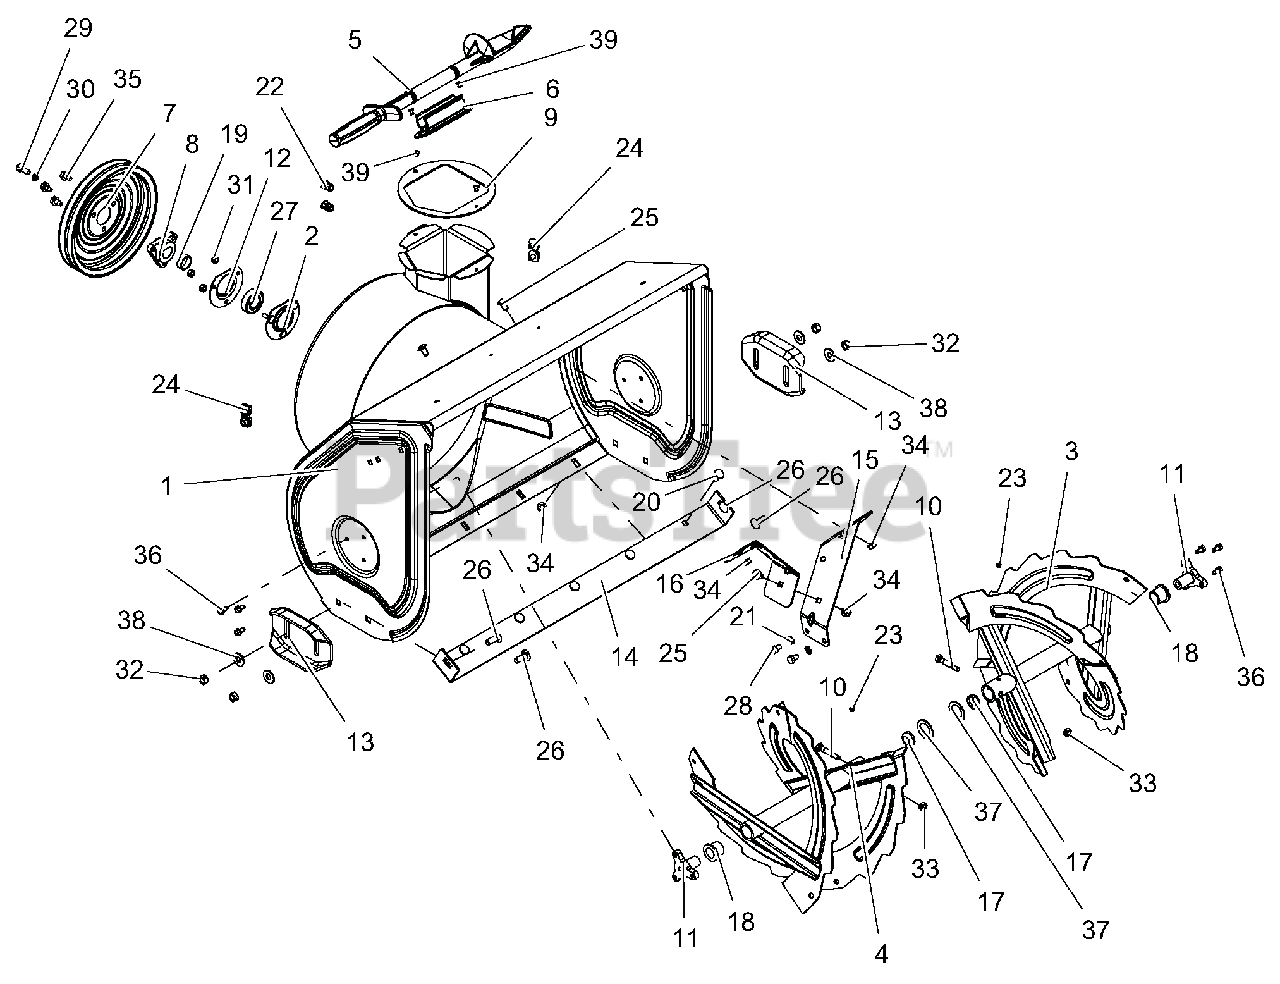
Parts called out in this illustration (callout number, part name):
1	BLOWER HOUSING, 28"
2	BEARING FLANGE
3	RAKE, LH W/ZERK - 28"
4	RAKE, RH W/ZERK - 28"
5	DEVICE, SNOW CLEAN OUT
6	MOUNT, SNOW CLEAN OUT
7	PULLEY, SPIN FORM DUAL GROOVE
8	PULLEY HUB, D-BORE .87 DELUXE
9	BAFFLE, DISCHARGE NECK
10	SHEAR BOLT SERVICE ASSEMBLY
11	SUPPORT, RAKE BUSHING
12	BEARING FLANGE
13	SKID SHOE, REVERSIBLE - ORANGE
14	BLADE, SCRAPER - 28"
15	BRACKET, GEARCASE SUPPORT - LH
16	BRACKET, GEARCASE SUPPORT - RH
17	PLUG, RAKE TUBE
18	BSHG-FLG, NY.778 ID X 1.018 OD
19	BSHG-SPCR .895IDX1.065ODX.353
20	BOLT, MODIFIED HEAD CARRIAGE
21	@WSHR-LK-EXT.326X.599X.031YWZC
22	NUT, THREADED INSERT .38-16
23	ZERK,FITTING .25X.125 DRIVE IN
24	SCR-TAP.31-18X.50 HWH TR YWZ
25	BLT-RDHDSQSHNK.31-18X.62 YZ-LK
26	@BLT-RDHDSHSQNK.38-16X1.0 G5YZ
27	BRG-BALL .876X1.75X.50 RSTFP
28	@BLT-HEX .31-18X.50 GR5 YWZC
29	BLT-HEX .31-24X.75 YWZC GR5
30	WSHR-LK .312X.097 HVY YWZC
31	@NUT-LK-CTR .25-20 YWZC
32	@NUT-LK-CTR .38-16 YWZC
33	@NUT-LK-CTR .31-18 YWZC
34	@NUT-LK-TOP-FLG .31-18 YWZC
35	@SCR-TAP .31-18X.50 HWH TR YWZ
36	SCR-TAP .25-20X.50 HWH TR YWZ
37	WSHR-FL-STL 1.010X1.505X.062YZ
38	@WSHR-FL-STL.438X1.00X.083 YWZ
39	RVT-POP .187 YZ
